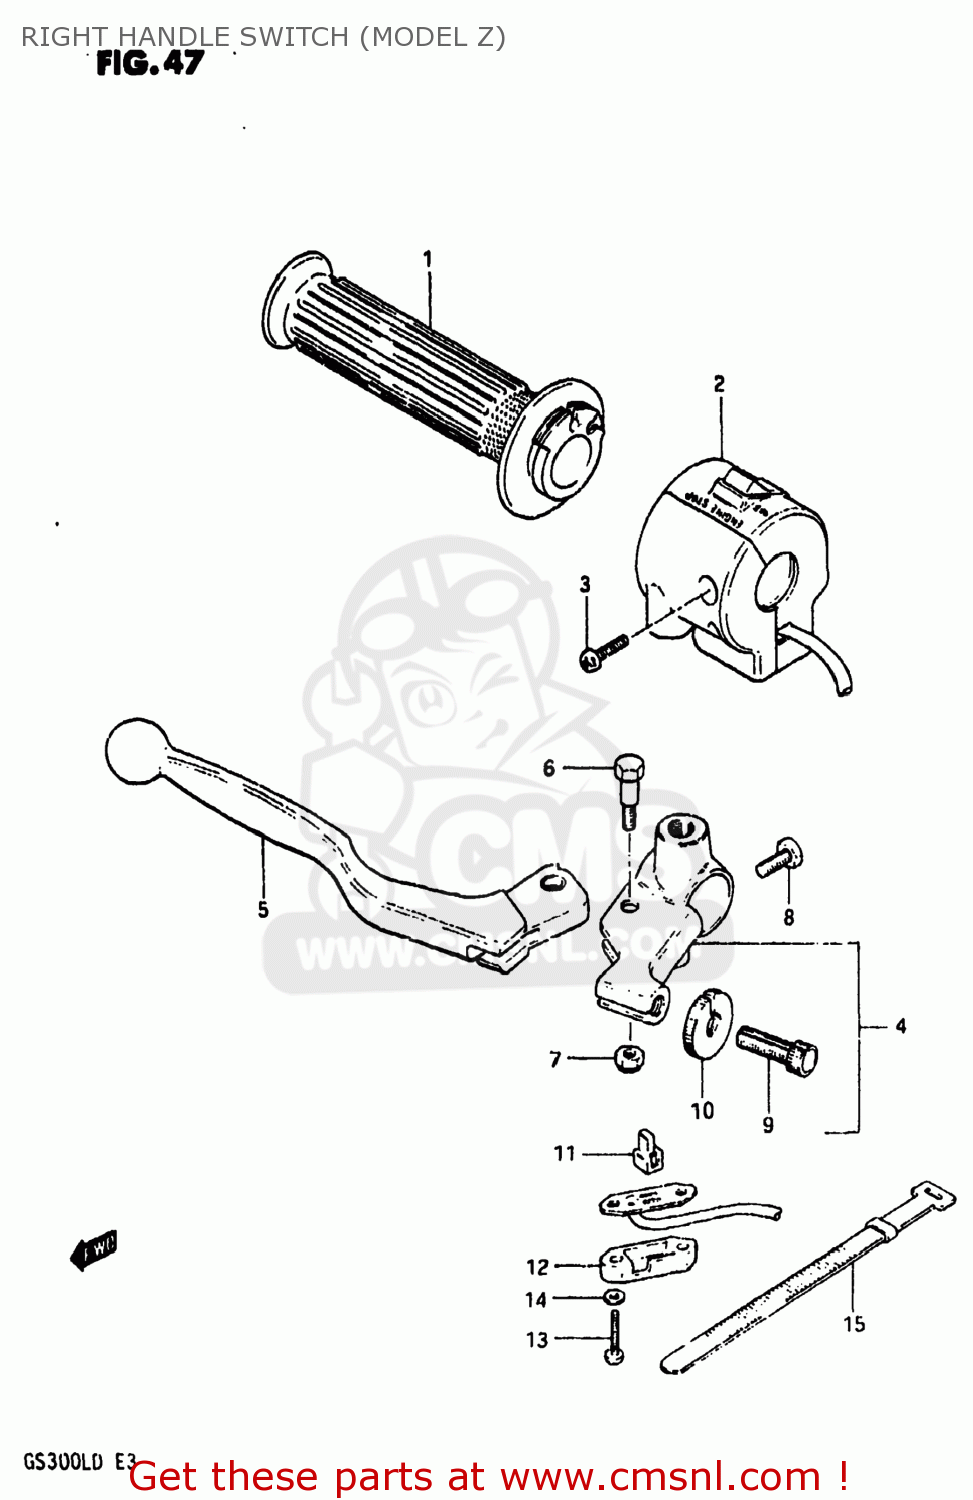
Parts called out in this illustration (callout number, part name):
1	GRIP,THROTTLE
2	SWITCH ASSEMBLY,HANDLE,RIGHT
3	SCREW
4	LEVER ASSEMBLY,BRAKE
5	LEVER,BRAKE
6	BOLT,LEVER
7	NUT 6MM
8	SCREW
9	ADJUSTER,CABLE
10	NUT,CABLE ADJUSTER
11	SWITCH ASSEMBLY
12	CLAMP(L:120)
13	BUTTON,STARTER
14	SPRING,STARTER BUTTON
15	CONTACT,STARTER BUTTON
